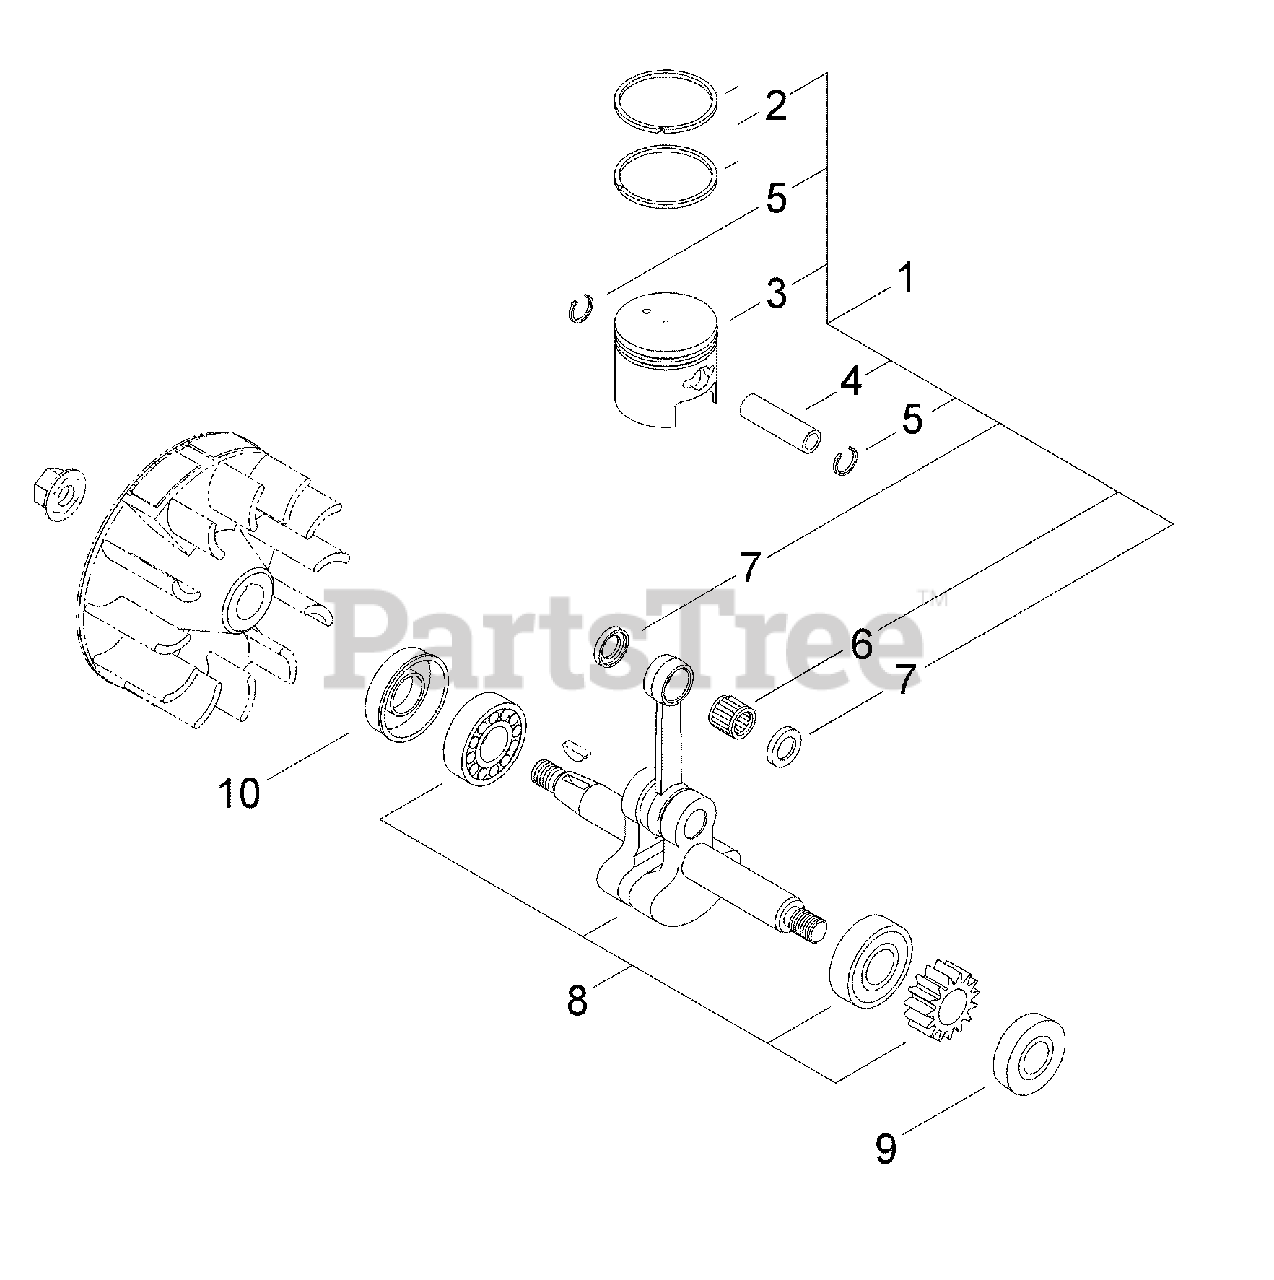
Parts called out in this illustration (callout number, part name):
1	PISTON KIT
2	RING, PISTON
3	PISTON
4	PIN, PISTON
5	RING, RETAINING
6	BEARING, NEEDLE
7	WASHER, THRUST - 10
8	CRANKSHAFT ASSY
9	SEAL, OIL - 12
10	SEAL, OIL
